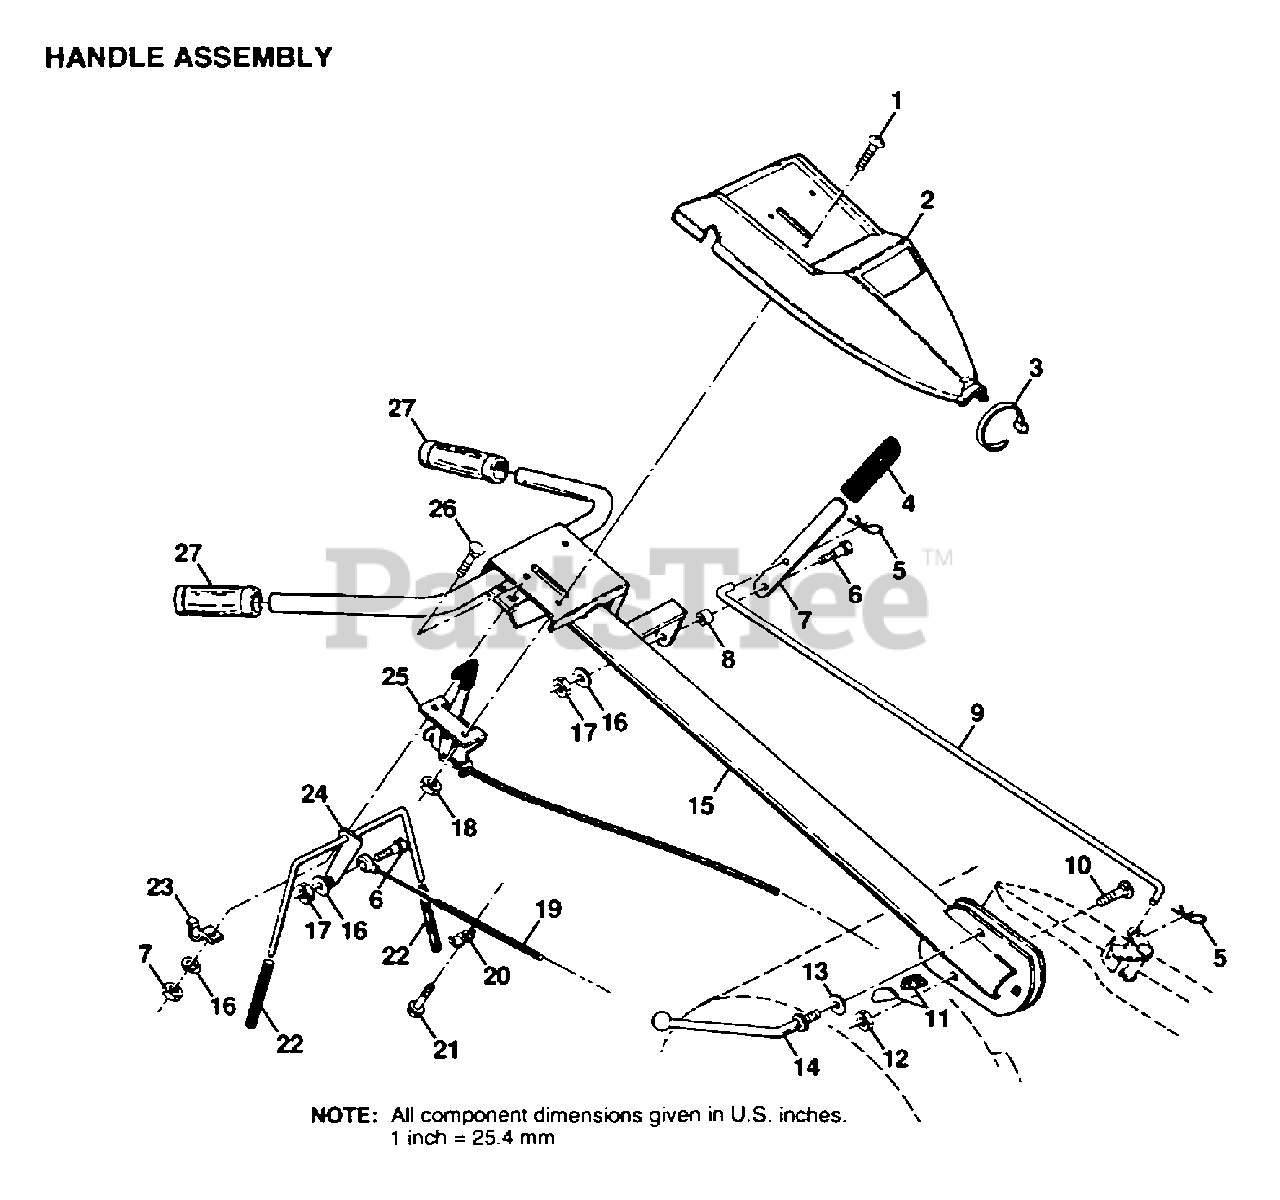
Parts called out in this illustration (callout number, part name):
1	SCREW
2	"PANEL,CONT TI"
3	TIE CABLE CRT
4	GRIP T
5	RETAINER M
6	BOLT, SHOULDER
7	SHIFT HANDLE CRT
8	GROMMET CRT
9	SHIFT ROD CRT
10	BOLT D
11	LOCK CRT
12	LOCKNUT
13	WASHER CRT
14	LEVER LOCK CRT
16	LOCKWASHER
19	CABLE.CLUTCH.CRT
20	CONDIUT CLIP T
22	GRIP BAR CRT
24	"ASSY CONTROL, BAR"
25	"CONT,THROTTLE"
26	BOLT
